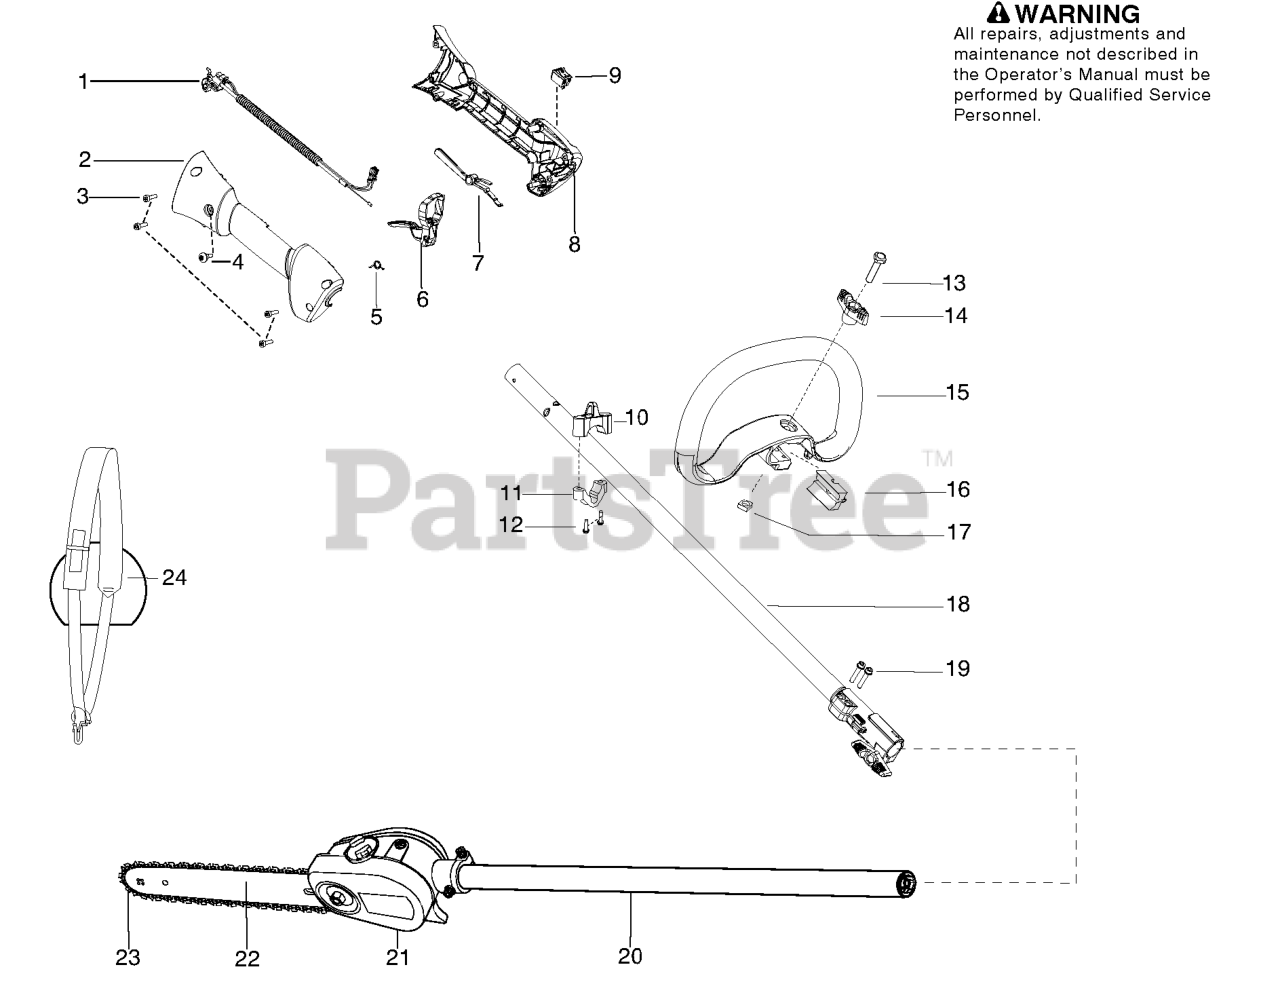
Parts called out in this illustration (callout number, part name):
1	ASSY CABLE / WIRE HARNESS
2	HSG THROTTLE RIGHT HVA
3	SCREW M4 X 1.75 PT 16MM
4	SCREW-10-14 X 1/2 PLASTITE
5	SPRING TRIGGER
6	TRIGGER THROTTLE HVA ORANGE
7	THROTTLE LOCKOUT HVA ORANGE
8	HSG THROTTLE LEFT HVA
9	SWITCH
10	CLAMP HARNESS UPPER
11	CLAMP HARNESS LOWER
13	SCREW M6X55
15	ASSY LOOP HANDLE
16	SPACER PLASTIC
18	DRIVESHAFT
20	KIT DRIVE SHAFT PRUNER
21	CUTTING HEAD ASSY
22	Bar - 12"
23	Chain - 12"
24	Harness - Diagonal with sign
